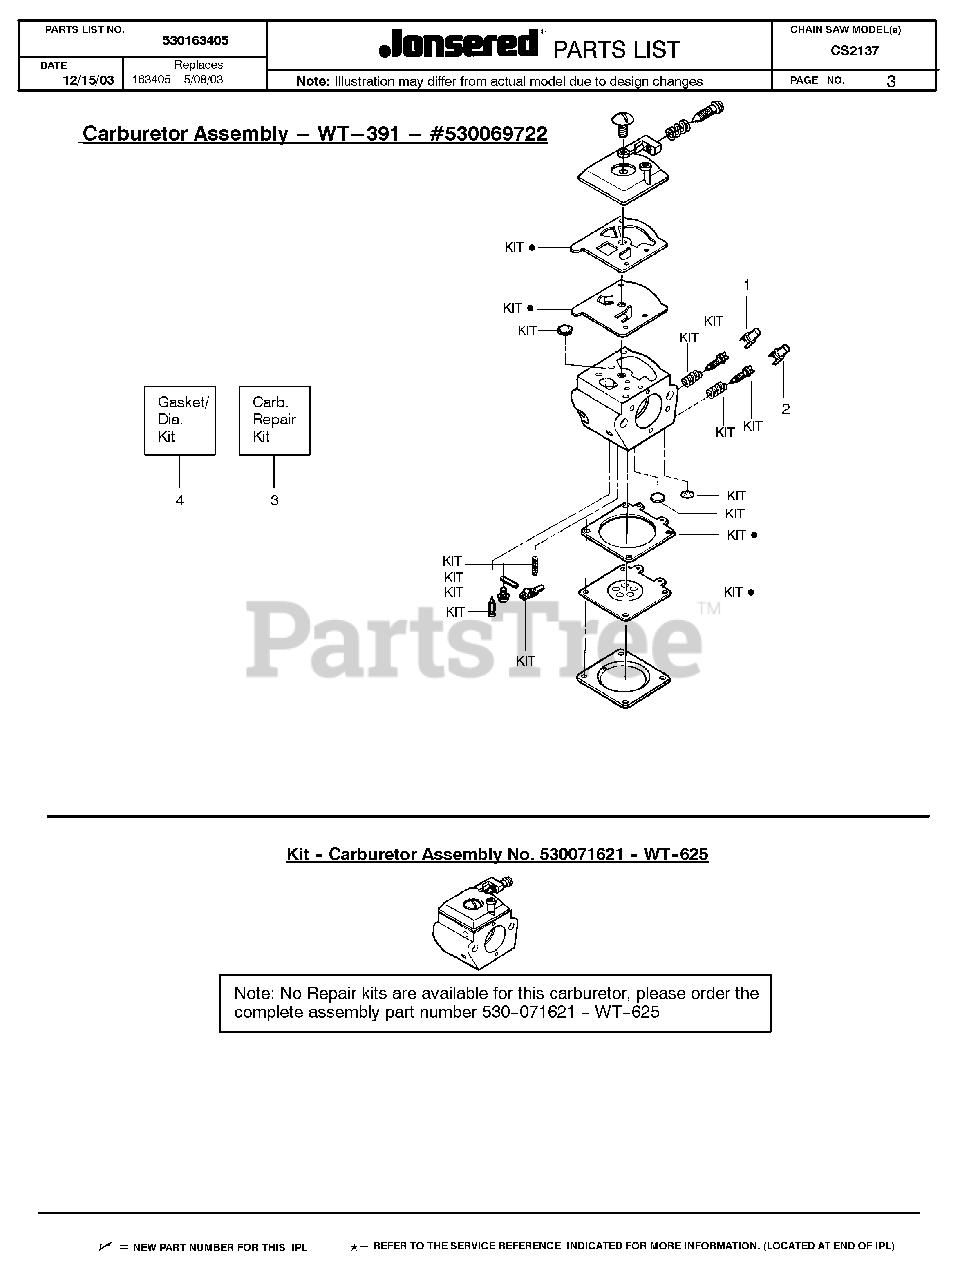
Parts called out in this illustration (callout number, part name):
1	LIMITER CAP-HIGH
2	LIMITER CAP-LOW
3	CARB REPAIR KIT
4	GASKET/DIAPHRAGM KIT
